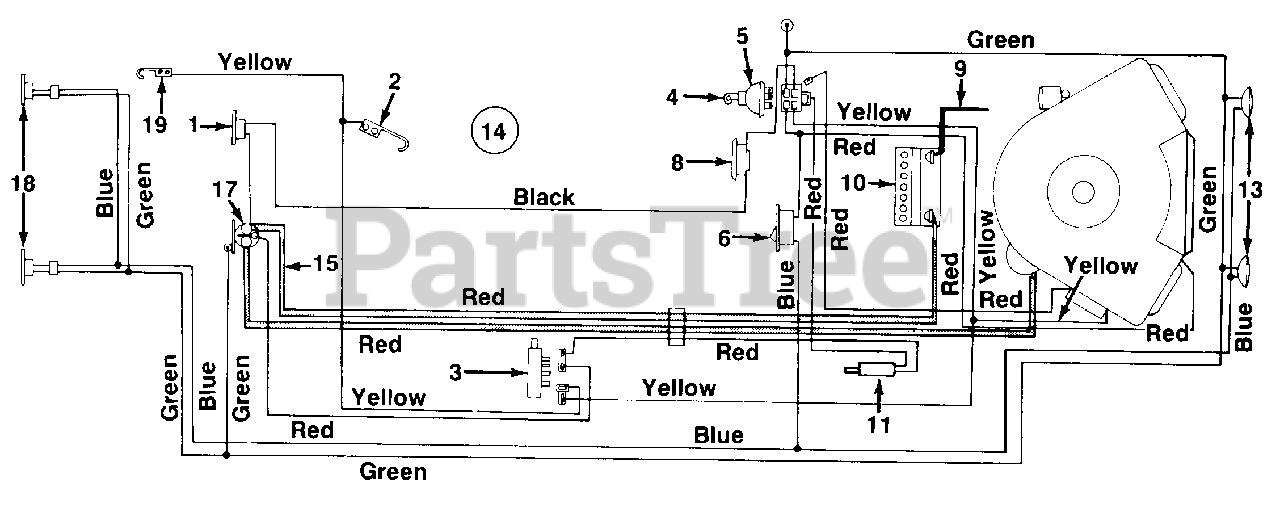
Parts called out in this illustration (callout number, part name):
1	Circuit Breaker
2	Spring Switch
3	Safety Switch Dpst.
4	Ignition Key
5	Ignition Switch
6	Headlight Switch
8	Ammeter
9	Grounding Wire 14.0" Lg .
10	12 Volt Battery
11	Safety Switch
13	Headlight
14	Wire Harness
15	Electric Wire 27.0" Lg.
17	Solenoid
18	Taillight
19	Spring Switch
